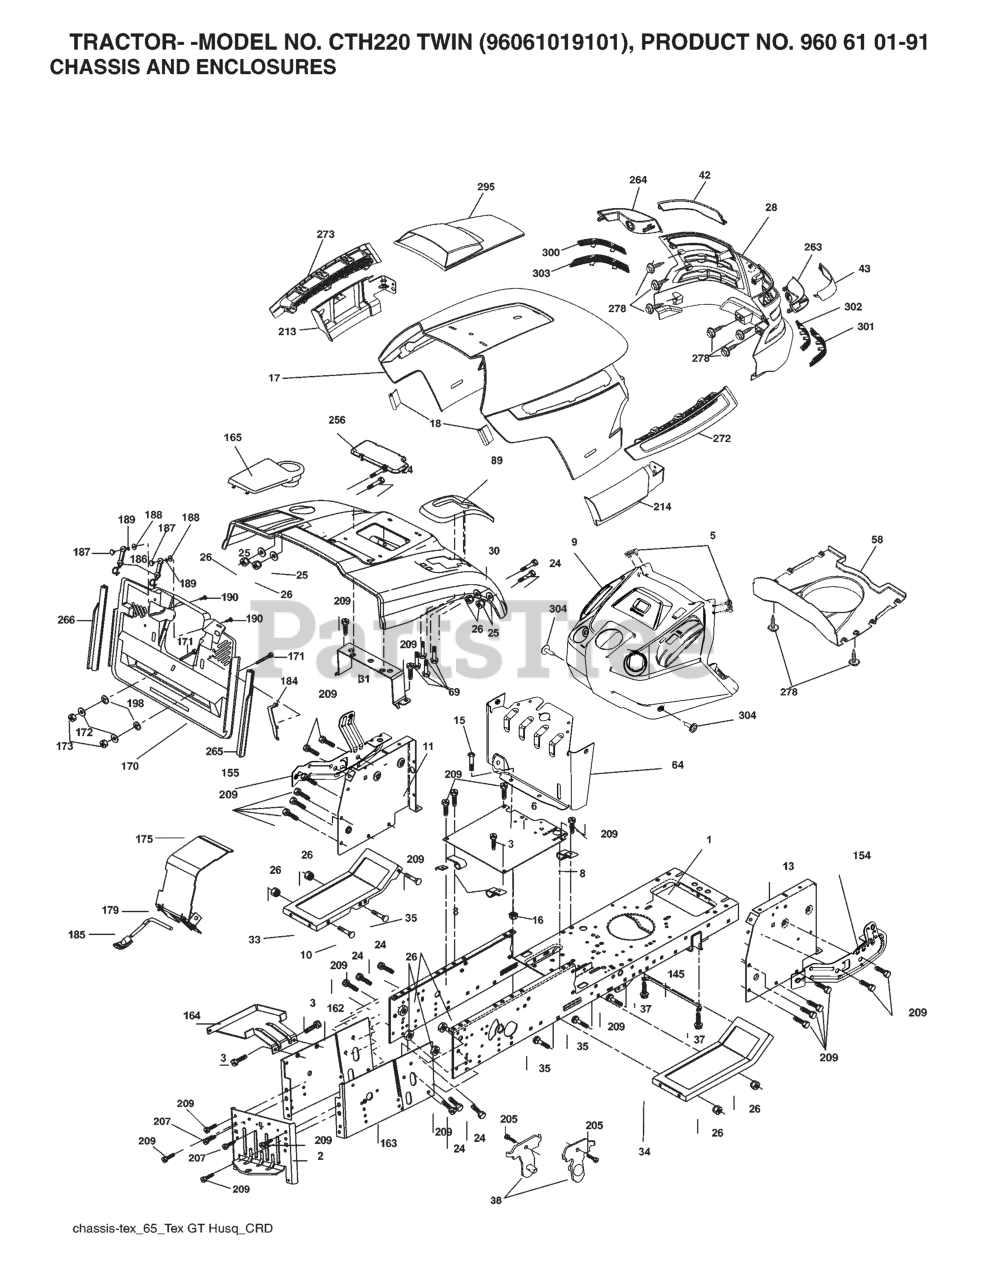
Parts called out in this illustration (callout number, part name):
2	DRAWBAR
3	SCREW 3/8-16X3/4
5	BUMPER DASH
6	PLATE
8	CLIP,INSULATOR
10	BOLT D
11	PANEL DASH LH
13	PANEL DASH RH
15	Screw, Machine, Truss Head 5/16-18 UNC x 3/4
16	NUT
17	HOOD
18	BUMPER.HOOD.TEX.HUSQVARNA
25	WASHER
26	NUT
28	GRILL.ASM.HUSQ.TG/CRD.W/TRIM
30	CONSOLE.CRD.AUTO.GRY
31	BRACKET SUPPORT FENDER
33	FOOTREST PNT LH
34	FOOTREST PNT RH
37	Screw 5/16-18 x 1/2 Hex, Self Tapping 5/16-18 x 1/2
38	BRACKET ASM PIVOT MOWER REAR
42	LENS.LH.TEX.GT.HUSQ.CL
43	LENS.RH.TEX.GT.HUSQ.CL
58	AIR.DUCT.HOOD.TEX.GT.HUSQ
69	SCREW.HI-LO.CONSOLE
89	CONSOLE.CRD.AUTO.GREY.2005
145	ROD.PIVOT.HOOD
162	BRACKET
163	BRACKET EXTEN CHASSIS RH CRD
165	RP.COVER.BATTERY.CRD.GREY
172	WASHER
175	DOOR TRAP
179	ROD PIVOT FBI
184	BRACKET.ACTUATOR.BAGGER.SRD
186	LATCH ASSY
187	WELDNUT
189	LOCKWASHER #10
190	SCREW
207	SCREW, 5/16-18 X 1/2
209	SCREW, 3/8-16X3/4
213	SKIRT.HOOD.SIDE.HUSQ.LH.GREY
214	SKIRT.HOOD.SIDE.HUSQ.RH.GREY
256	COVER FENDER CRD
263	BEZEL.RH.TEX.GT.HUSQ
264	BEZEL.LH.TEX.GT.HUSQ
265	SEALING
266	SEALING
272	VENT.SIDE.HOOD.HUSQ.RH.GREY
273	VENT.SIDE.HOOD.HUSQ.LH.GRAY
278	SCREW
295	VENT.ASM.HOOD.TOP.TEX.
300	INSERT.HEX.GRILL.HUSQ.
301	INSERT.HEX.GRILL.HUSQ.GREY
302	INSERT.HEX.GRILL.HUSQ.
303	INSERT.HEX.GRILL.HUSQ.
304	SCREW 14-20 X 5/8
